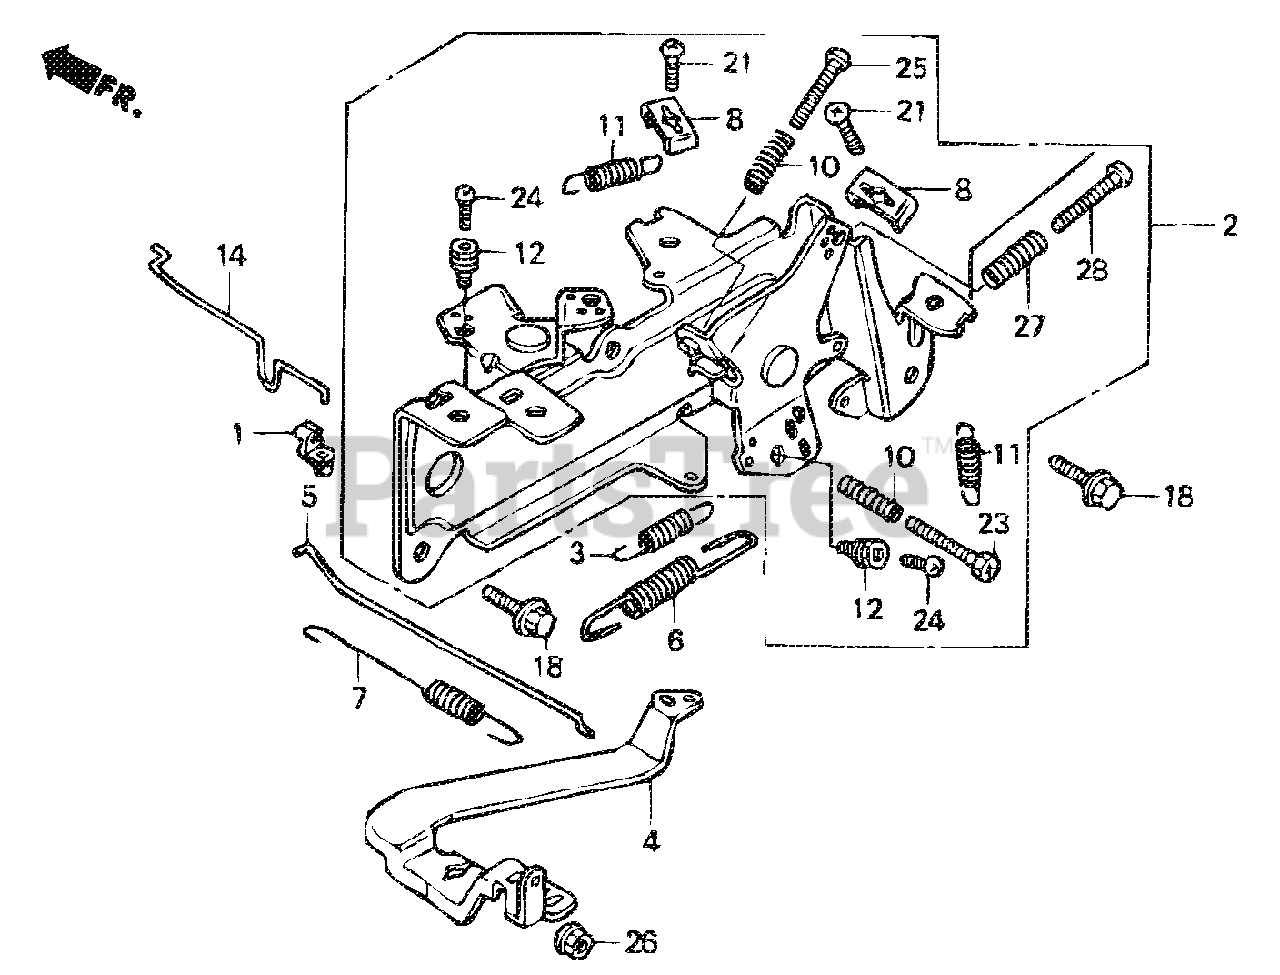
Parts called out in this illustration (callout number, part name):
1	Joint, Rod
2	Control Assembly
3	Spring, Starter
4	Arm, Governor
5	Rod, Governor
6	Spring, Governor
7	Spring, Throttle Return
8	Holder, Cable
10	Spring, Control Adjusting
11	Spring, Cable Return
12	Holder, Cable
14	Rod, Choke Control
18	Bolt, Flange (6x14)
21	Bolt, Slot (5x16)
23	Bolt, Slot (5x25)
24	Bolt, Recessed (4x6)
25	Screw, Pan (5x25)
26	Nut, Flange (6mm)
